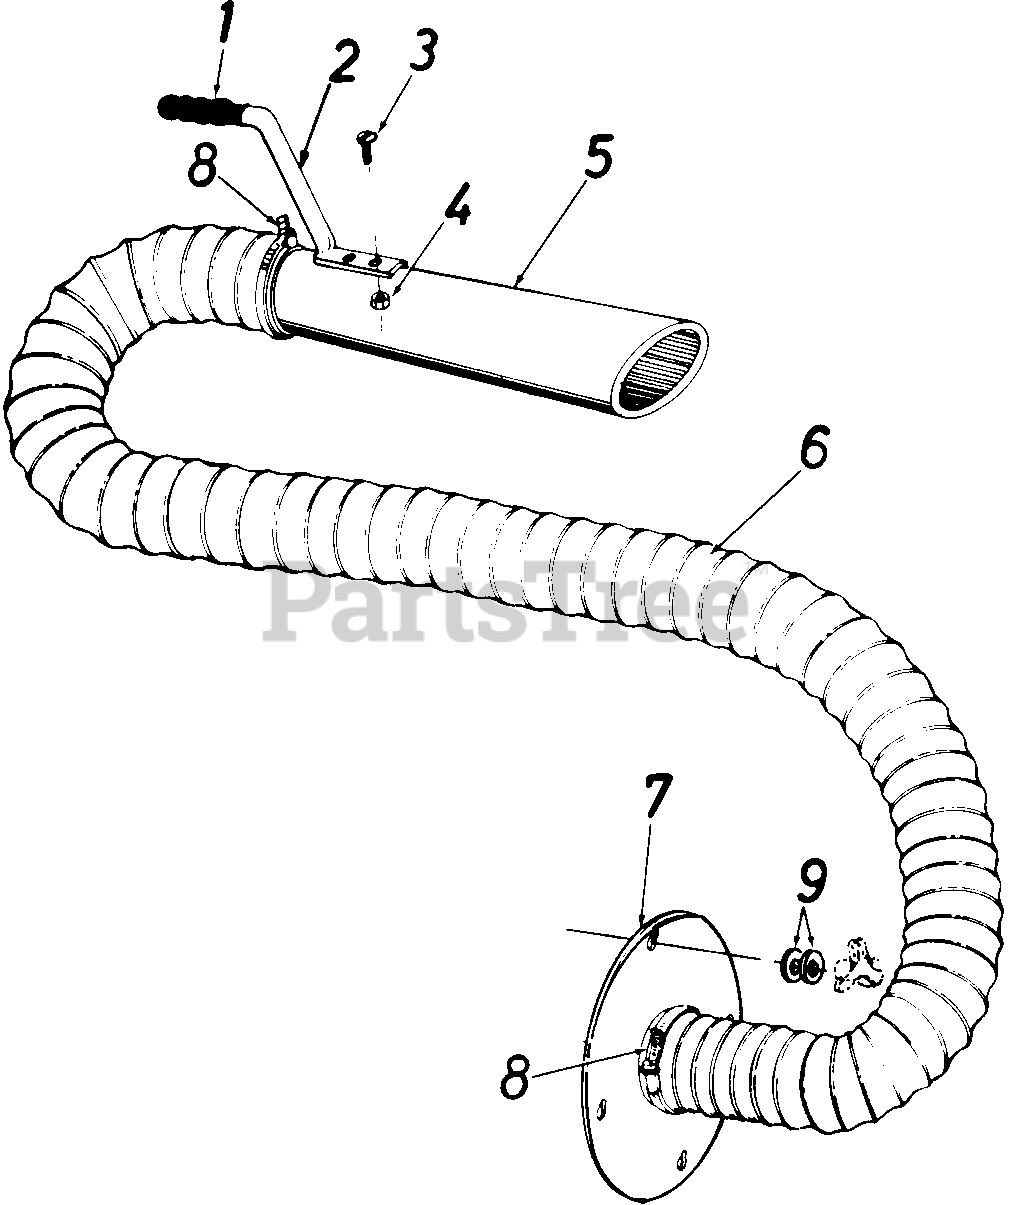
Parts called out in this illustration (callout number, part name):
1	Handle Grip
2	Handle
3	Truss Sems Scr. 10-24 x 1/2" Lg.*
4	Hex Nut 10-24 Thd.*
5	Hose Nozzle
6	Flexible Hose 4" Dia. x 10' Lg.
9	Flat Washer .34 I.D. x 1.12 O.D.
